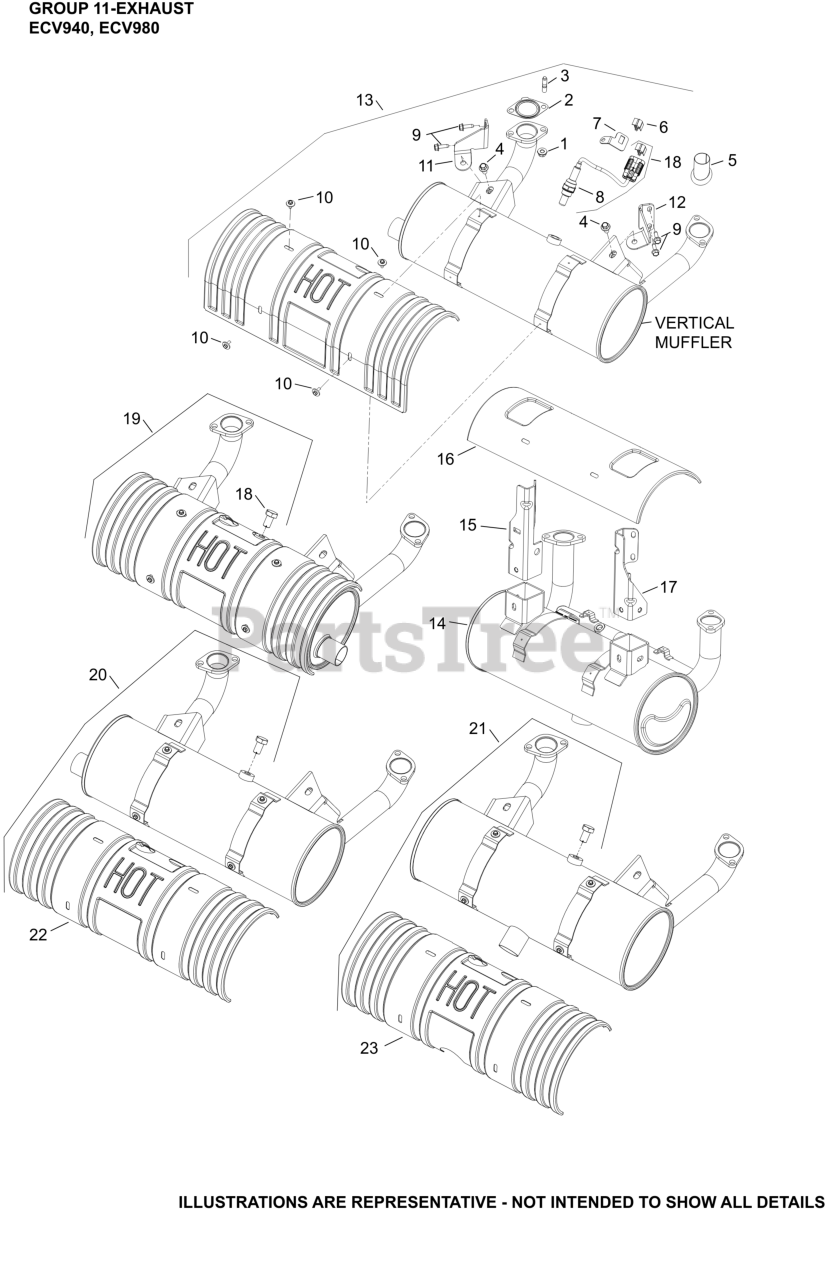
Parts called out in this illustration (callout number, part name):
2	GASKET, EXHAUST
3	STUD, METRIC EXHAUST
4	SCREW, THREAD FORMING
5	LINER, EXHAUST PORT
6	CLIP, O2 SENSOR
7	BRACKET, OXYGEN SENSOR
18	KIT, O2 SENSOR
